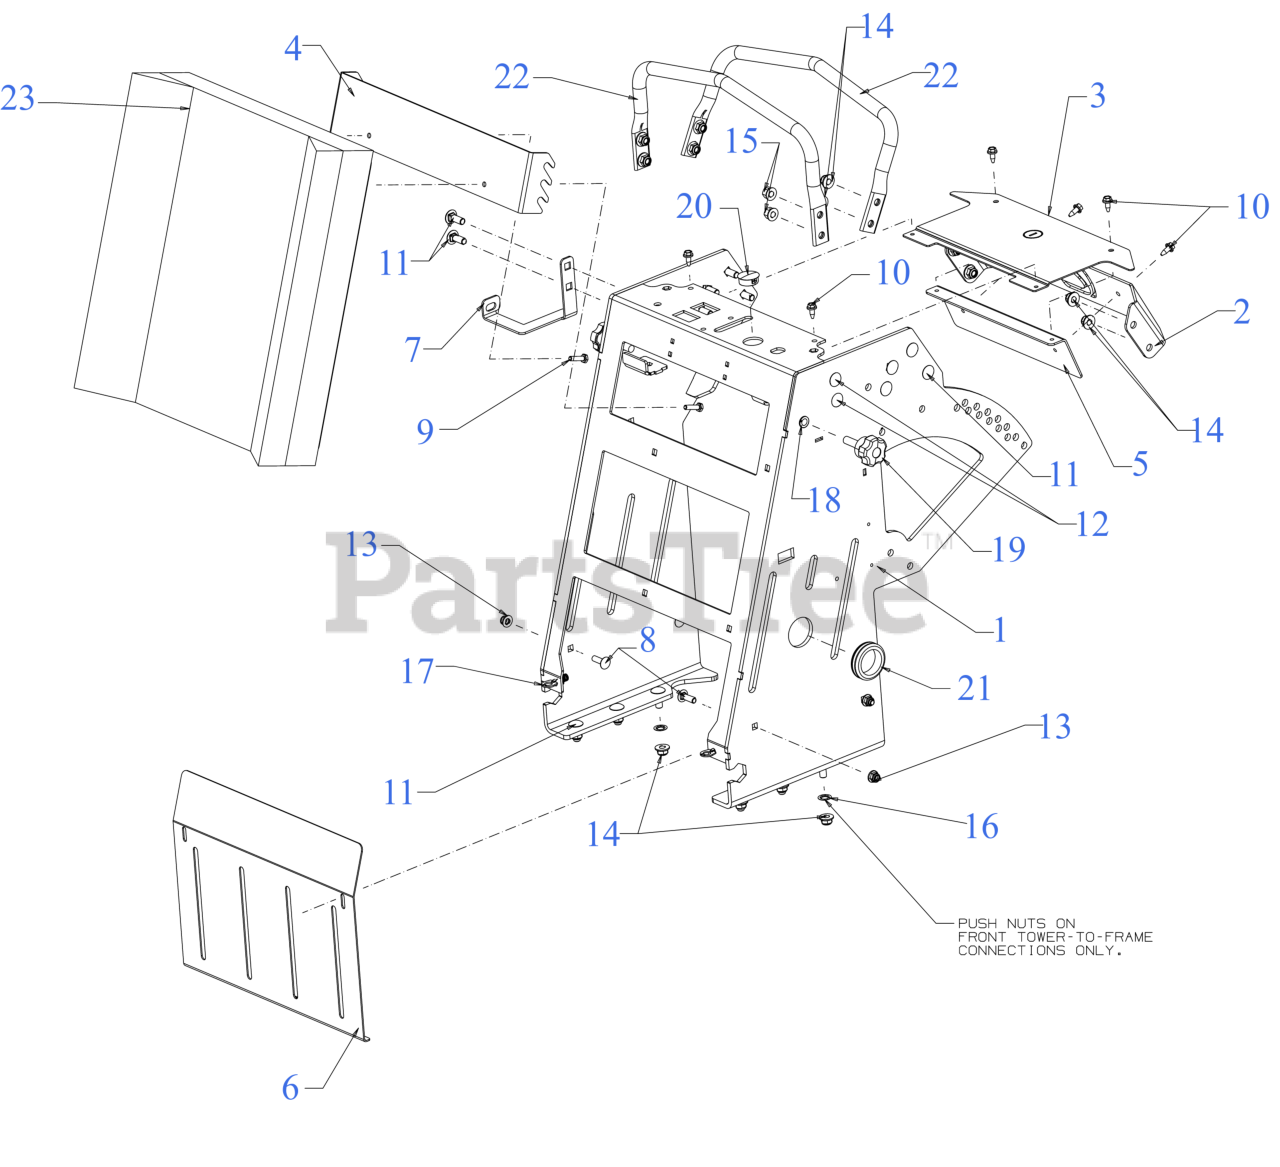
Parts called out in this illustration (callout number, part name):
1	CONTROL BASE
2	FRONT CONTROL BASE
3	DASH PANEL
4	LEG PAD BRACKET
5	DASH SUPPORT
6	REAR COVER BRACKET (LOWER)
7	FUEL TANK BRACKET (UPPER)
8	CARRIAGE BOLT 5/16-18 x 1.00
9	SCREW 1/4-20 X1.00 GR5
10	SCREW 1/4-20X.625
11	CARRIAGE BOLT 3/8-16 x 1.00 GR5
12	CARRIAGE BOLT 3/8-16 x .75
13	FLANGE LOCK NUT 5/16-18
15	NUT-CTRLCK FLG HEX
17	PANEL LATCH
18	RIV NUT 3/8-16
19	SEAT ADJUST KNOB 3/8-16 x 1.50
20	PANEL PLUG
21	RUBBER GROMMET (1.50X2.13X.563)
22	CRUISE TUBE
